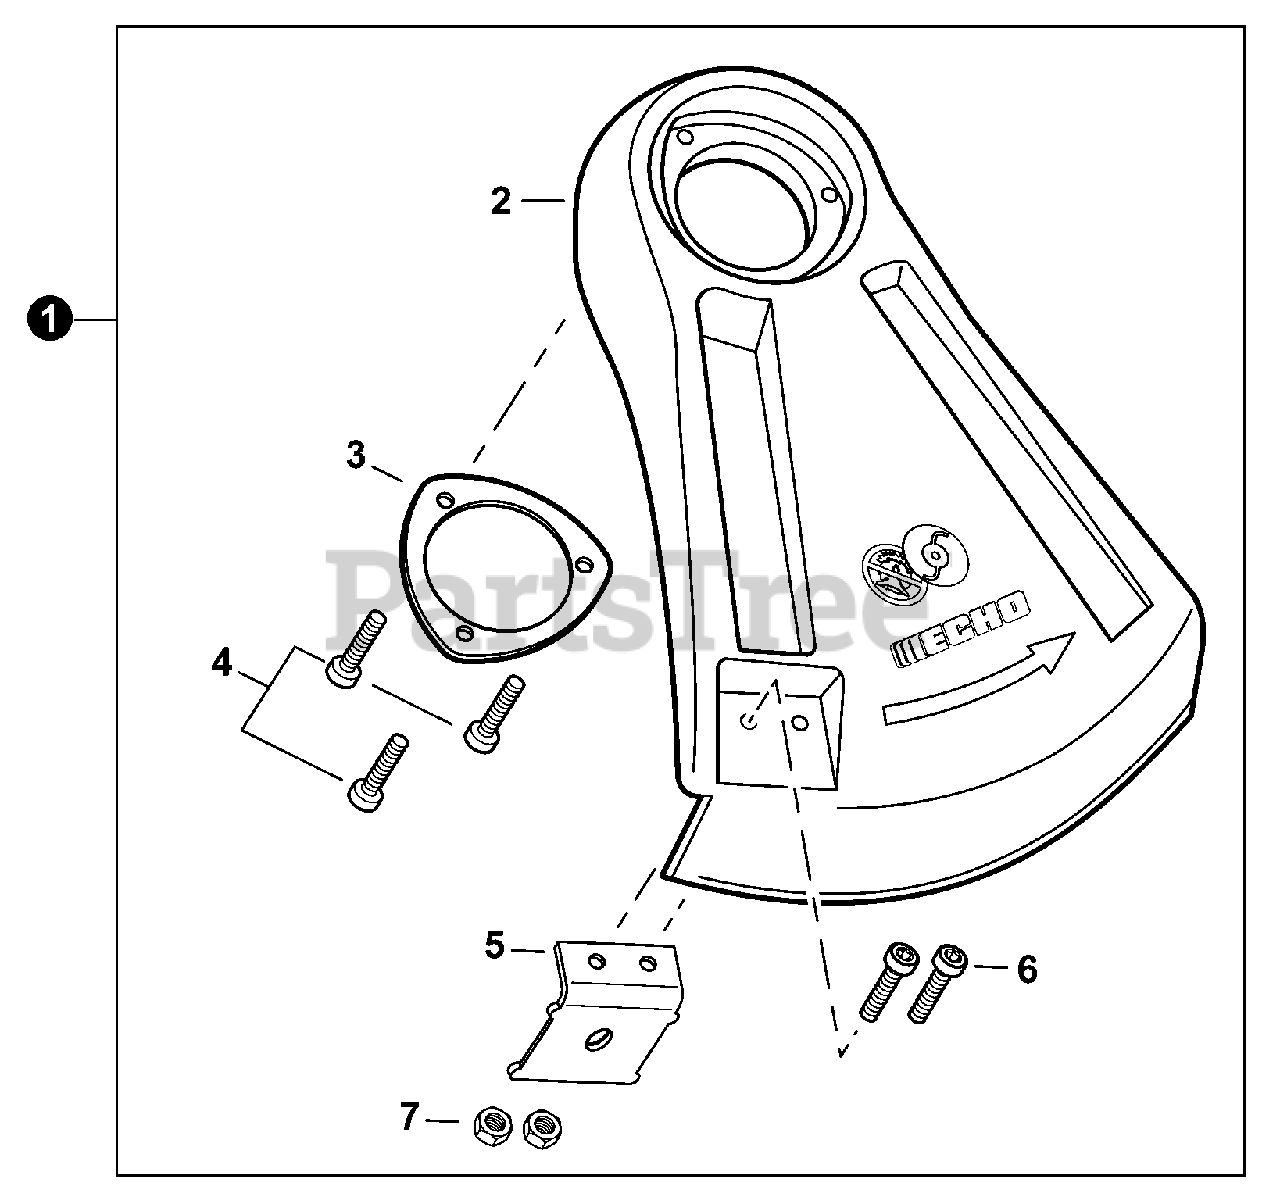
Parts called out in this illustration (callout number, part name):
1	DEBRIS SHIELD KIT
2	SHIELD, DEBRIS
3	PLATE, SHIELD Ø49.5 MM
4	BOLT, TORX 5×16
5	CUTTER, LINE
6	BOLT, TORX 5×12
7	NUT M5
